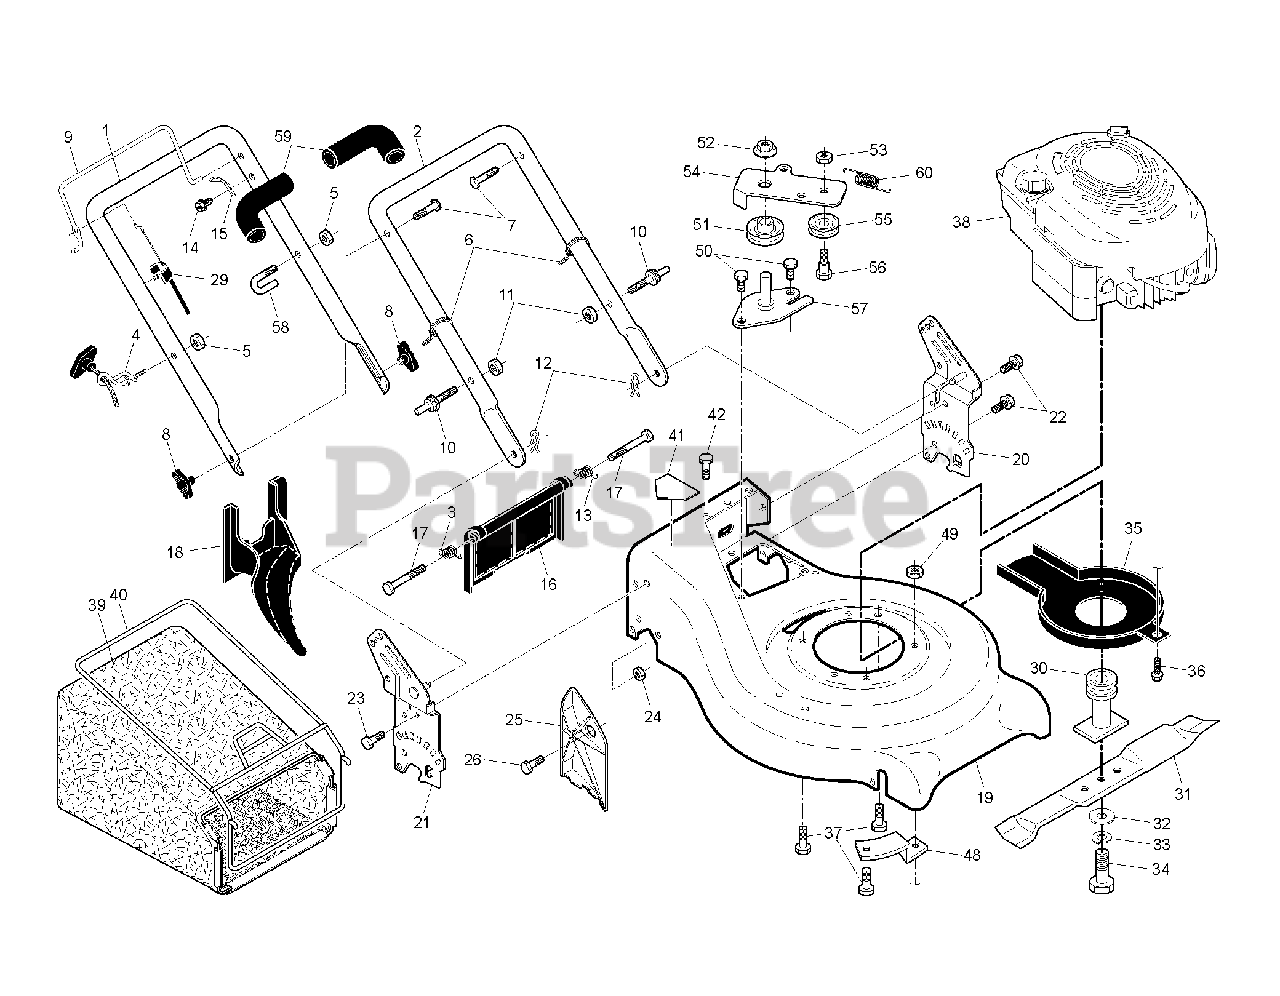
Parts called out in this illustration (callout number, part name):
2	HANDLE LOWER
3	SPRING, REAR DOOR, RH
4	GUIDE.ROPE.STD.BLK.ZIN
5	NUT
6	TIE GUIDE
7	BOLT, HANDLE 5/16-18X1.75
8	KNOB, DEFLECTOR
11	NUT.CENTERLOCK.5/16-
12	HAIRPIN COTTER
13	SPRING.LH.REAR.DOOR.21.RWGD
15	BRACKET UPSTOP
16	DOOR.REAR.PLASTIC.21.RWGD.BLAC
18	PLUG.MULCHER.RGD.21.
20	BRKT.ASM HNDL
21	BRKT.ASM.HNDL
22	SELF-TAPPING SCREW 5/16-18X3/4
23	BOLT, HEX HEAD 5/16-18
24	NUT.71038.31-18.HEX.NYLOCK
25	CLIPPING DEFLECTOR
29	SNAP-ON.ZONE.CABLE.ASS
30	BLADE ADAPTOR / PULLEY
31	BLADE.21.PUSH
32	WASHER,HARDEN
33	LOCKWASHER
34	SCREW, HEX HD 3/8-24 X 1-3/8
35	DEBRIS SHEILD
36	SCREW.HEX.WSH
37	BOLT 3/8-16X1-1/8
40	FRAME.CATCHER.21.RGD.AG
41	DECAL.INTERNATIONL.CUTFINGER
48	BRACKET
51	PULLEY.IDLER
52	NUT
54	ARM.IDLER
55	IDLER PULLEY
57	BRACKET.IDLER.ASM.EZ
59	GRIP.HANDLE.FOAM.WIDE.(1 SIDE)
60	SPRING, RETURN
